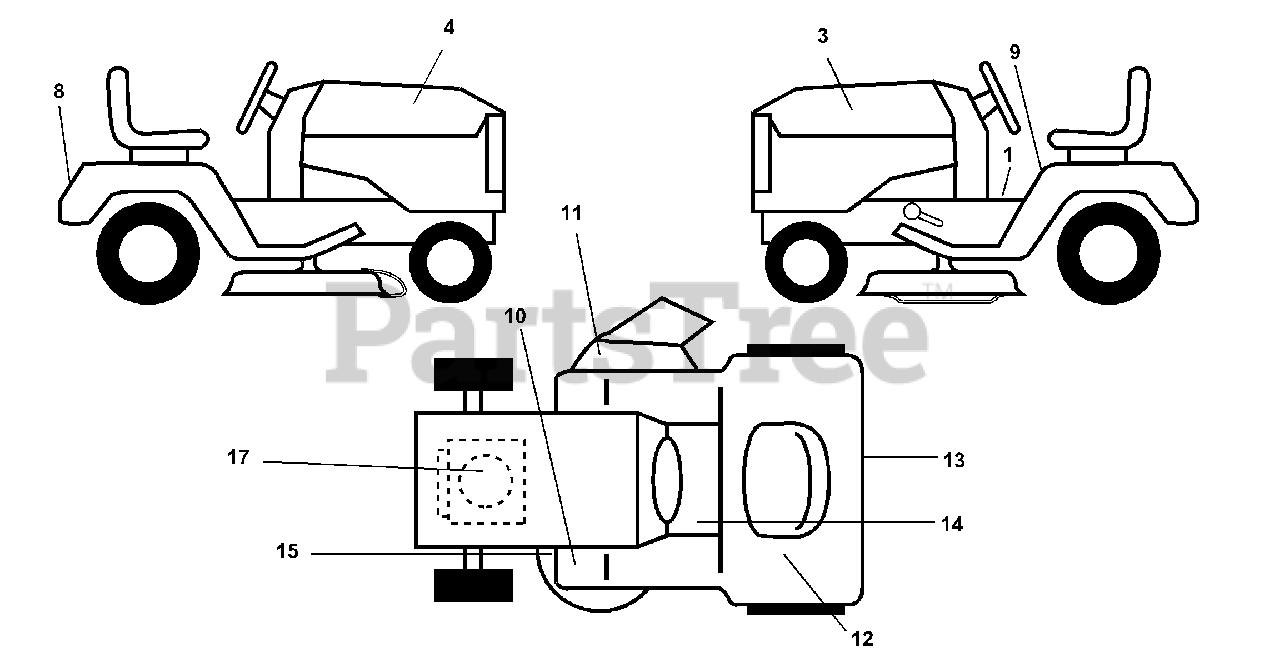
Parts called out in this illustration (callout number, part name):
1	Decal Instruction Dash Eng/fr
3	Decal Hood LH
4	Decal Hood RH
8	Decal Fender Logo
9	Decal Caution Fender Eng/fr
10	Decal Clutch/brake Eng/fr
11	Decal Warning Multi-Language
12	Decal Bat Dan/Poi P/L Sym WPN
13	Decal Drawbar CNTRL MVT HYD LT
14	Decal SDL COLD START HYD E/F
15	Decal V-Belt Schematic
17	Decal Engine Kohler 13 HP
